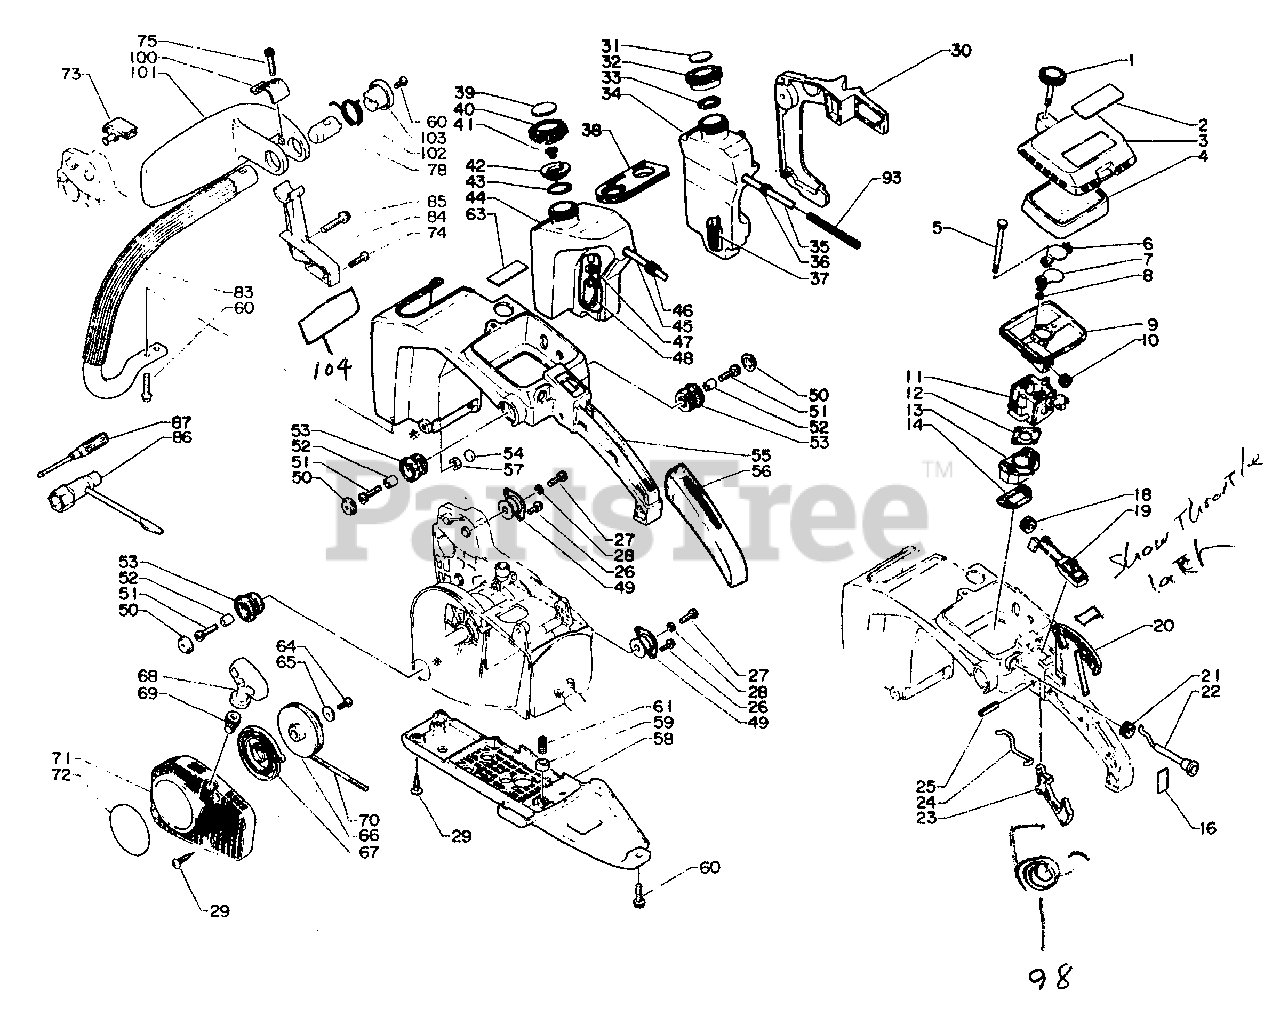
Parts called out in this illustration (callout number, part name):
1	THUMBSCREW
2	LABEL
3	COVER, AIR FILTER
4	FILTER, AIR
6	PLATE, PREVENT
7	SHUTTER, CHOKE
8	SPACER
9	CASE, AIR FILTER
10	GROMMET, RUBBER
11	CARBURETOR - C1S-K3A
12	GASKET, INTAKE
13	INSULATOR, INTAKE
14	GASKET, INTAKE
16	LABEL - CHOKE
19	SWITCH
20	CONTROL, THROTTLE
21	GROMMET
22	ROD, CHOKE
23	TRIGGER, THROTTLE
24	ROD, THROTTLE
25	PIN, SPRING 5×25
26	SCREW 4×10
27	BOLT 4×12
28	WASHER, SPRING 4 MM
29	SCREW - 4×16 -- TAPPING
30	SUPPORTER
31	LABEL - CHAIN OIL
32	CAP, OIL TANK
33	GASKET, CAP
34	TANK, OIL
35	PIPE, OIL
36	GROMMET
37	FILTER, OIL
38	CONNECTOR
39	LABEL - FUEL MIX
40	CAP
41	VALVE, CHECK
42	HOLDER, CHECK VALVE
43	O-RING 22
44	TANK, FUEL
45	OIL PIPE KIT
47	WASHER 5.5×12×0.8
48	FILTER, FUEL
49	CUSHION
50	CAP, CUSHION
51	BOLT, HEX 4×20
52	COLLAR 4.2×7×9.5
53	CUSHION
54	SPACER
55	HANDLE, REAR
56	GRIP
57	NUT
58	SUPPORT
59	STOPPER
60	SCREW 5×20
61	SPRING
63	LABEL - NOISE
64	SCREW 4×12
65	WASHER 4.1×15.5×1T
66	REEL, ROPE
67	SPRING, RECOIL
68	GRIP, STARTER
69	GUIDE, ROPE
70	ROPE, STARTER 3.0×850
71	CASE
72	LABEL - ECHO
73	COVER
74	SCREW - 4×20 -- TAPPING
75	SCREW 5×35
78	SPACER, HANDLE
83	HANDLE, FRONT
84	SUPPORTER
85	SCREW 5×30
86	T-WRENCH 10×19 MM
87	SCREWDRIVER, PHILLIPS
98	SPRING, THROTTLE RETURN
101	GUARD
103	RETAINER
104	LABEL - KICK BACK
